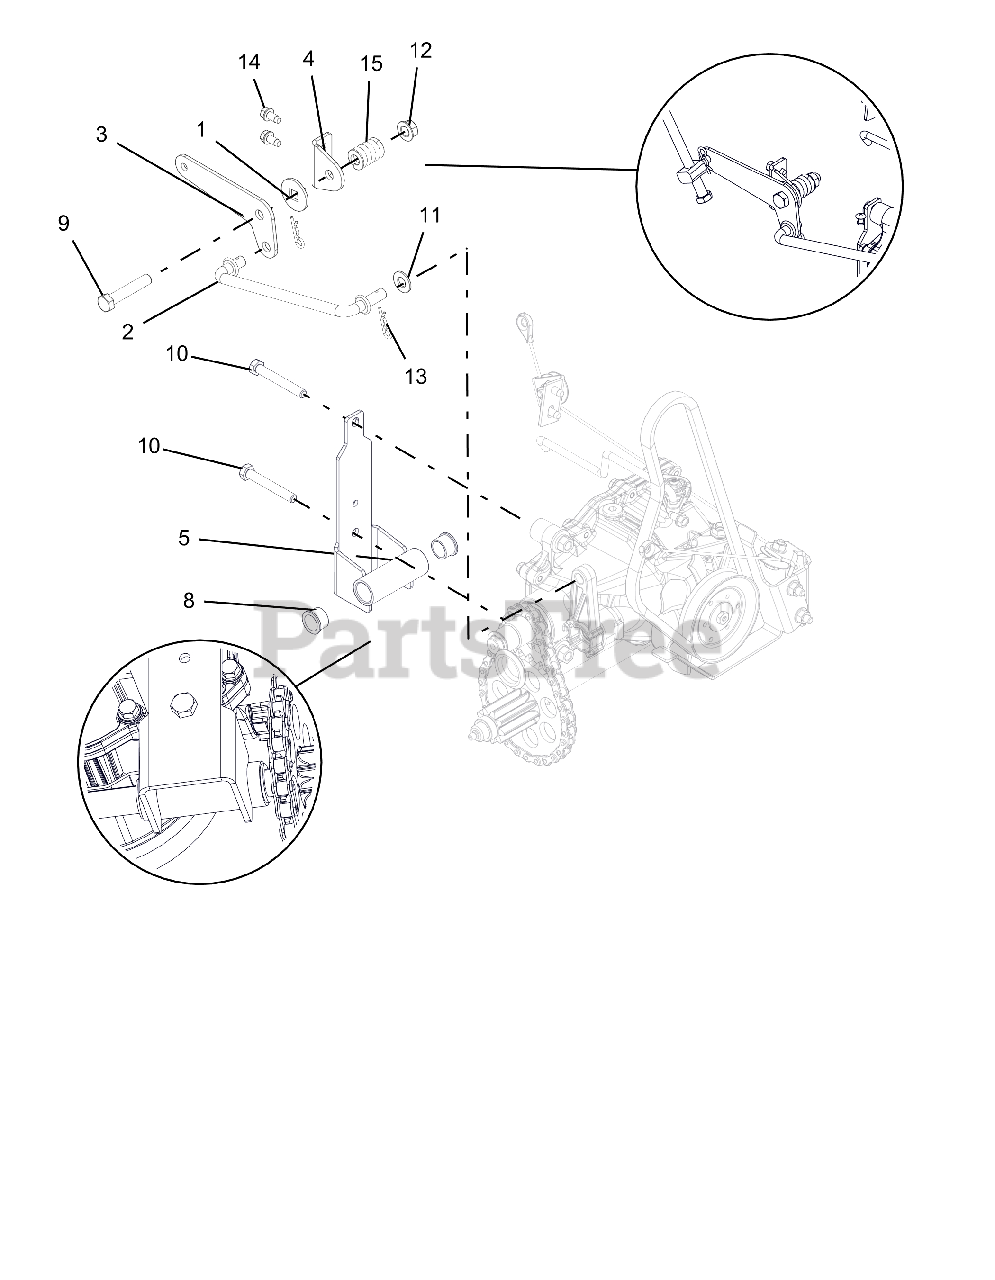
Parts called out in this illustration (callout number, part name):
1	FRICTION WASHER
2	ROD, HYDRO TRANS SHIFT
3	PIVOT, HYDRO TRANS SHIFT
4	BRACKET, HYDRO SHIFT PIVOT
5	TRANS MOUNT, TENSIONING, WHEEL
7	TUBE, TRANS MOUNT, TENSIONING
8	BSHG-FLG .625X.750X.500X.875
9	@BLT-HEX .38-16X2.00 GR5 YWZC
10	@BLT-HEX .31-18X2.25 GR5 YWZC
11	@WSHR-FL-STL.406X.812X.065 YWZ
12	@NUT-LK-TOP-FLG .38-16 YWZC
13	PIN-HAIR INT .08X.18X1.18 YWZC
14	SCR-TAP .25-20X.50 HWH TR YWZ
15	SG-COMP .187X.56X1.62
